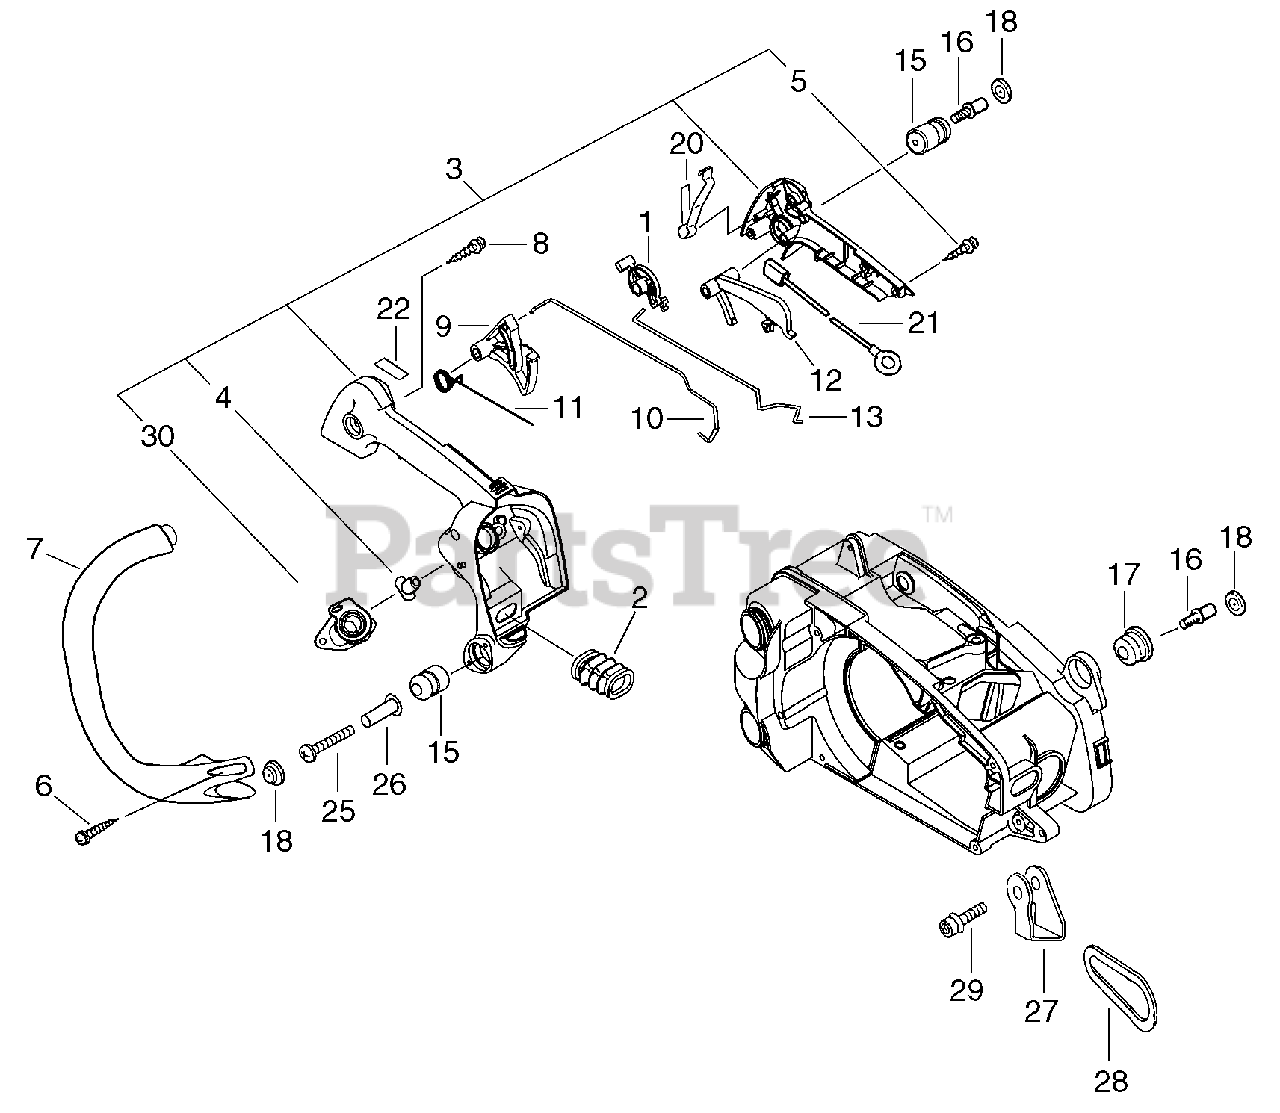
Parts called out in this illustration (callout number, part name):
1	LEVER, CONTROL
2	PIPE - INTAKE
3	HANDLE - REAR
5	SCREW - 4X16
6	SCREW - 4X16
7	HANDLE - FRONT
8	SCREW - 5X20 -- TAPPING
9	TRIGGER, THROTTLE
10	ROD, THROTTLE
11	SPRING, TRIGGER
12	LOCKOUT, THROTTLE
13	ROD, CHOKE
15	CUSHION
16	STUD, THREADED
17	CUSHION
18	CAP, CUSHION
20	TERMINAL - GROUND
21	LEAD - GROUND
25	SCREW - 4X35 -- TAPPING
27	BRACKET, STRAP
28	HANGER KIT
29	SCREW - 4X25
30	BELLOWS, INTAKE
